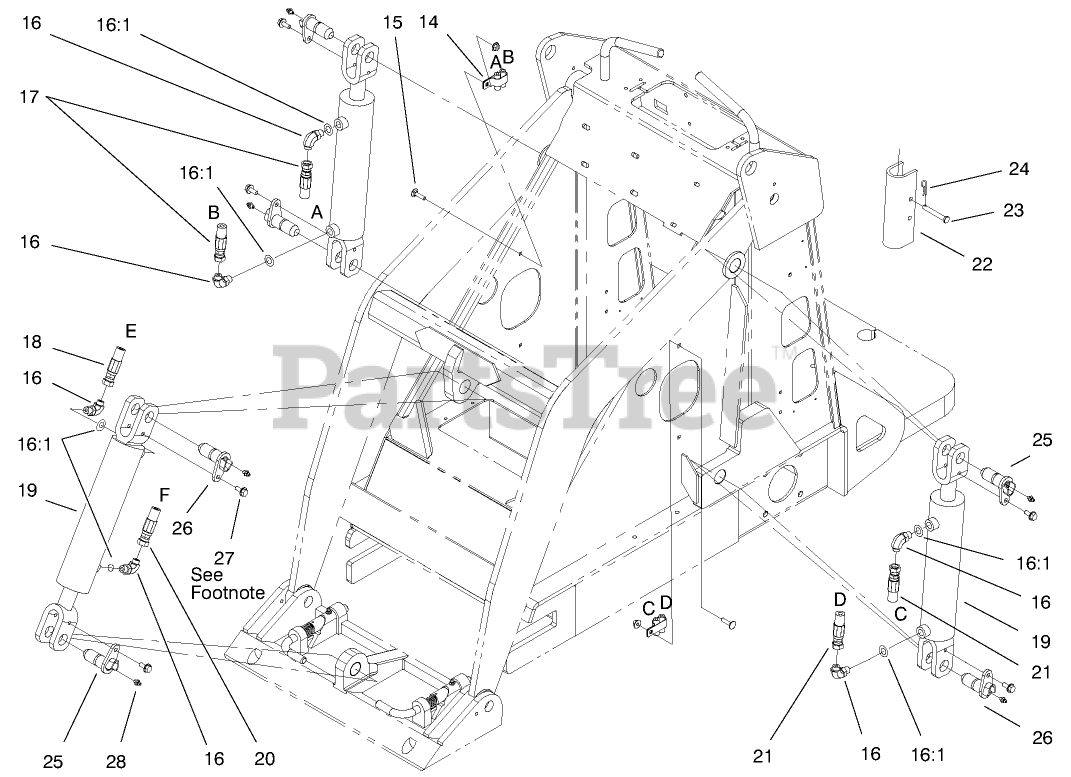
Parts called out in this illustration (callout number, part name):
14	CLAMP-R, DOUBLE
15	BOLT-CARR
16	FITTING-ELBOW, 90 DEG
16:1	O-RING
17	HOSE-HYD
18	HOSE-HYD
19	Hydraulic Cylinder
20	HOSE-HYD
21	HOSE-HYD
22	Lock-Cylinder
23	PIN-CLEVIS
24	PIN-HAIR
25	ASM - PIVOT PIN, AU
26	ASM - PIVOT PIN, AU
27	SCREW-HH
28	FITTING-GREASE
